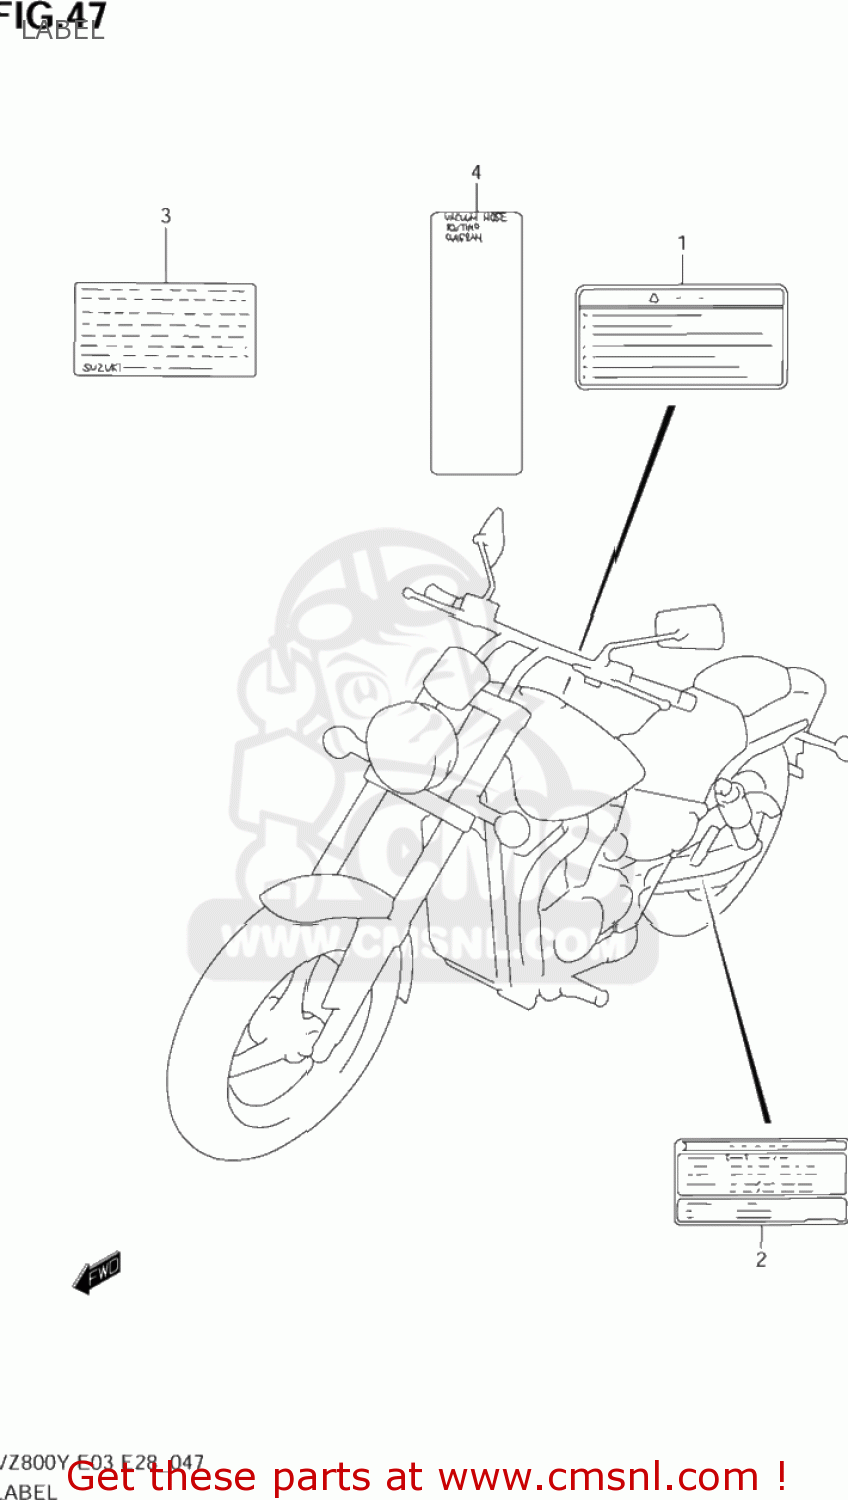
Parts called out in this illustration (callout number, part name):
1	LABEL,GENERAL WARNING
2	LABEL,TIRE AIR PRESSURE
3	LABEL,MANUAL NOTICE
4	LABEL (VACUUM HOSE ROUTING)
5	MANUAL,OWNER'S
